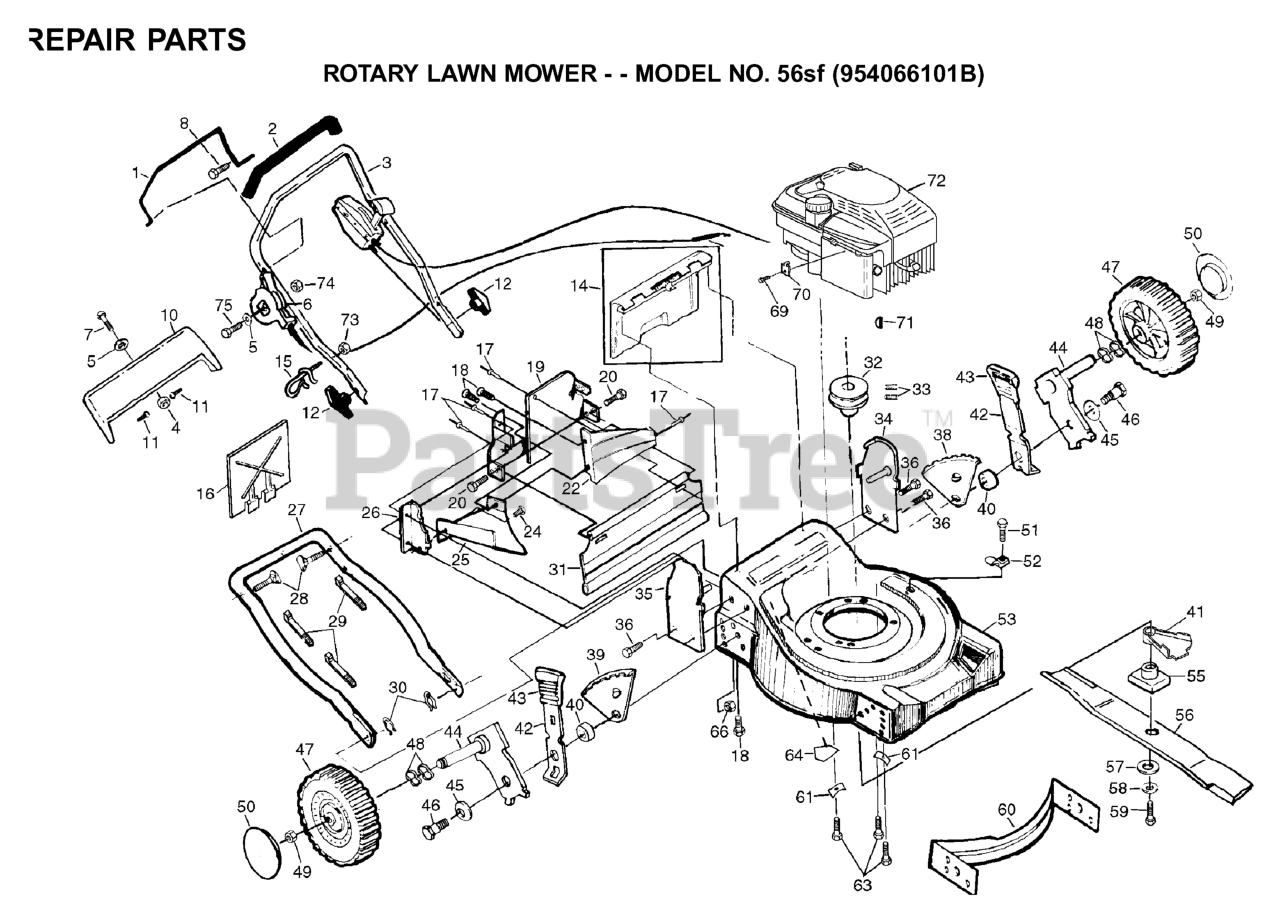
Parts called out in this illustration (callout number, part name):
1	CONTROL BAR
2	HANDLE GRIP
3	UPPER HANDLE
4	NUT
6	THROTTLE CONTROL
7	SCREW
10	TRIM PLATE
12	HANDLE KNOB
15	ROPE GUIDE
16	MULCHER PLATE
17	RIVET BLIND
20	HINGE SCREW
22	REAR BAFFLE
25	DISCHARGE BAFFLE
26	SIDE BAFFLE
27	HANDLE, LOWER PM
28	HANDLE BOLT
29	TIE GUIDE
30	HAIRPIN COTTER
31	REAR SKIRT
32	ENGINE.PULLEY.FWG
36	SCREW
38	WHEEL ADJ BRKT RF-LR
39	WHEEL ADJ BRKT RR-LF
40	SPACER PM
41	DEBRIS SHIELD
42	SELECTOR SPRING
43	SELECTOR KNOB
44	AXLE ARM ASSY FT
45	WASHER.BELLEVILLE (3 2 LB)
46	BOLT
47	WHL & TIRE ASSEMBLY
48	WAVE WASHER
49	HEX FLANGE LOCKNT
51	TAPPING SCREW
52	GUIDE CLIP PM
55	BLADE ADAPTOR
57	WASHER,HARDEN
58	LOCKWASHER
59	SCREW, HEX HD 3/8-24 X 1-3/8
60	FRONT BAFFLE
61	WASHER.ENGINE.BZP
63	BOLT
64	DECAL HYT
66	LOCKNUT PM
69	SCREW.HEX.HEAD.WASHER.10-16
71	HI PRO KEY PM WSL
73	NUT
74	NUT
75	SCREW 1/4-20X1.75
